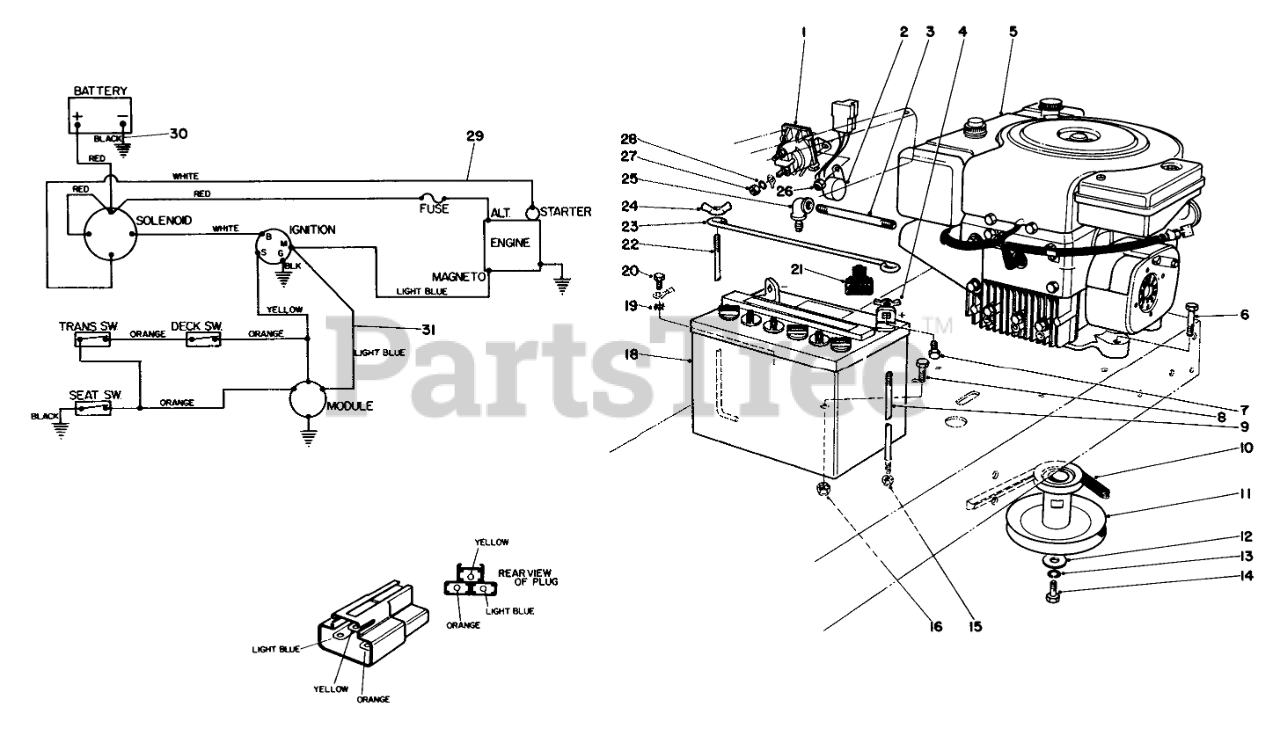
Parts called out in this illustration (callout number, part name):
1	SOLENOID
2	Module Interlock
3	NIPPLE
4	NUT-WING
5	Engine
6	SCREW-HH
7	SCREW-HH
8	SCREW-HH
9	BATTERY BOLT
10	V-BELT, TRACTION
11	PULLEY
12	WASHER
13	WASHER-LOCK
14	SCREW-HH
15	NUT-KEPS
16	NUT-LOCK, CONE
18	Battery
19	WASHER-LOCK, INTERNAL
20	SCREW-HHF
21	BOOT-TERMINAL
22	ROD-SUPPORT, BATTERY
23	BATTERY HOLD DOWN
24	WING NUT
25	ELBOW-90 DEGEE
26	NUT-LOCK, CONE
27	NUT-JAM
28	WASHER-LOCK
29	Wiring Harness
30	Wire-Battery to Ground
31	Wiring Harness
